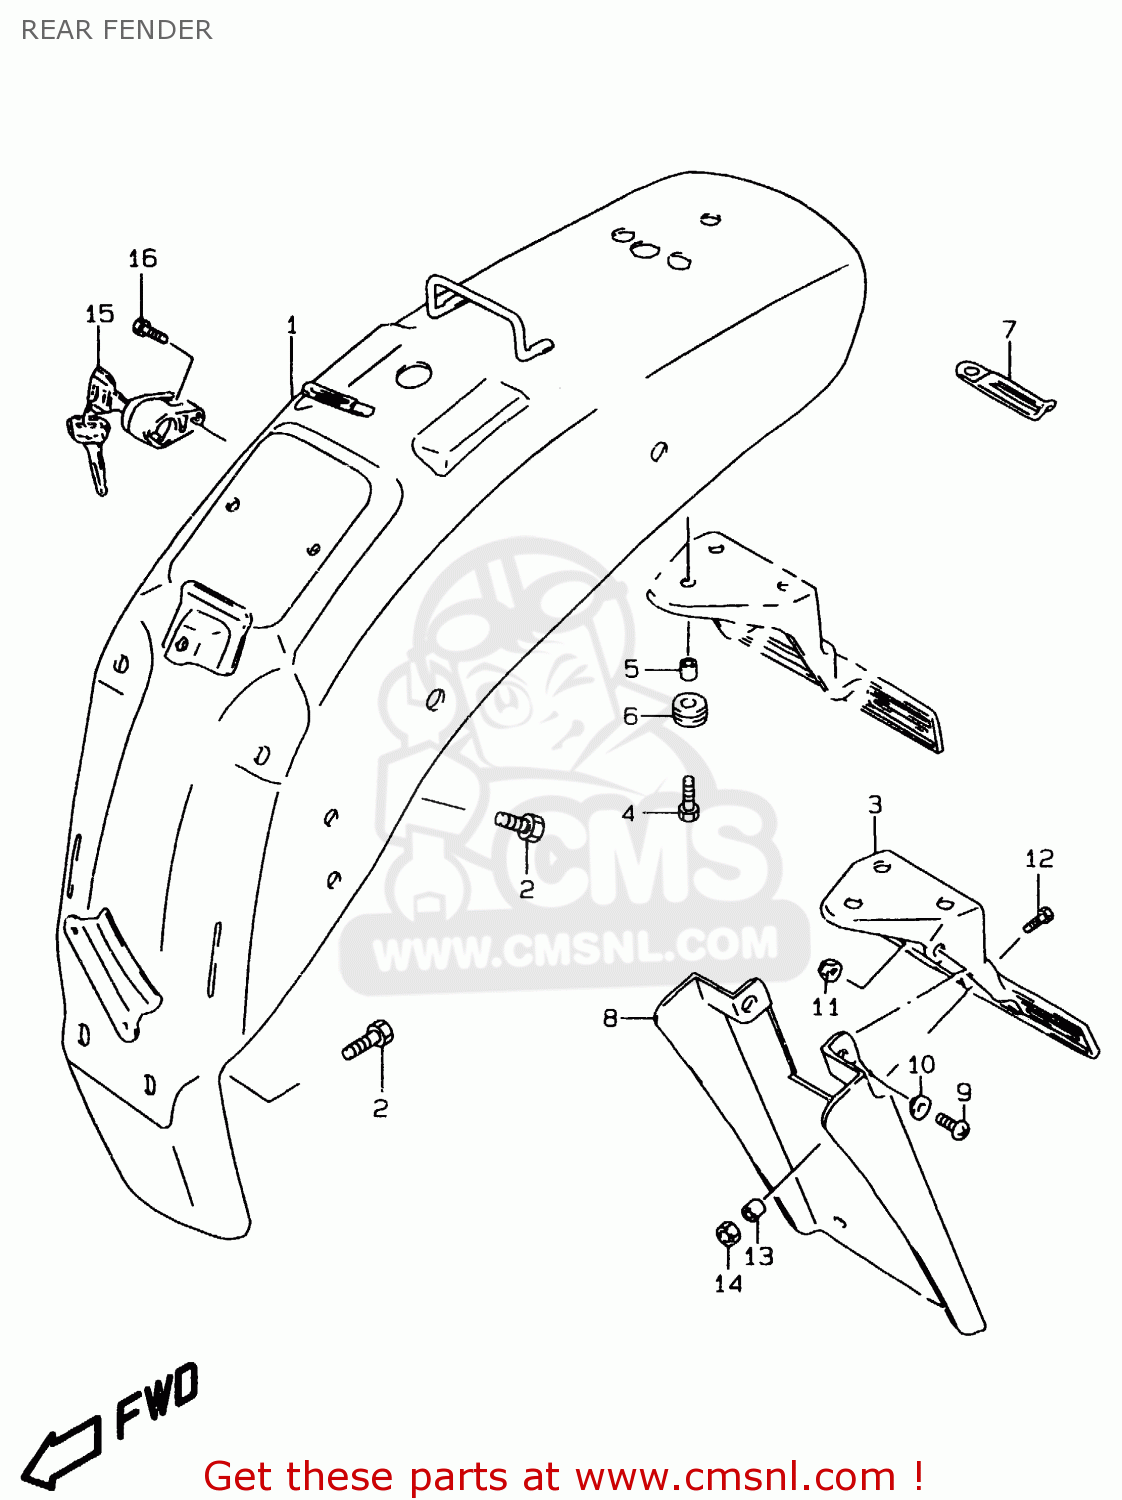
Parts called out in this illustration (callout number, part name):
1	FENDER COMP,REAR
2	BOLT 8X25
3	BRACKET,LICENSE PLATE
4	BOLT(6X20)
5	SPACER(6.5X9X9)
6	CUSHION
7	CLAMP(L:45)
8	EXTENSION,RR FENDER
9	SCREW
10	WASHER
11	NUT
12	SCREW, 6X20
13	SPACER(6.2X8.3X6.1)
14	NUT
15	LOCK SET,HELMET
16	SCREW
